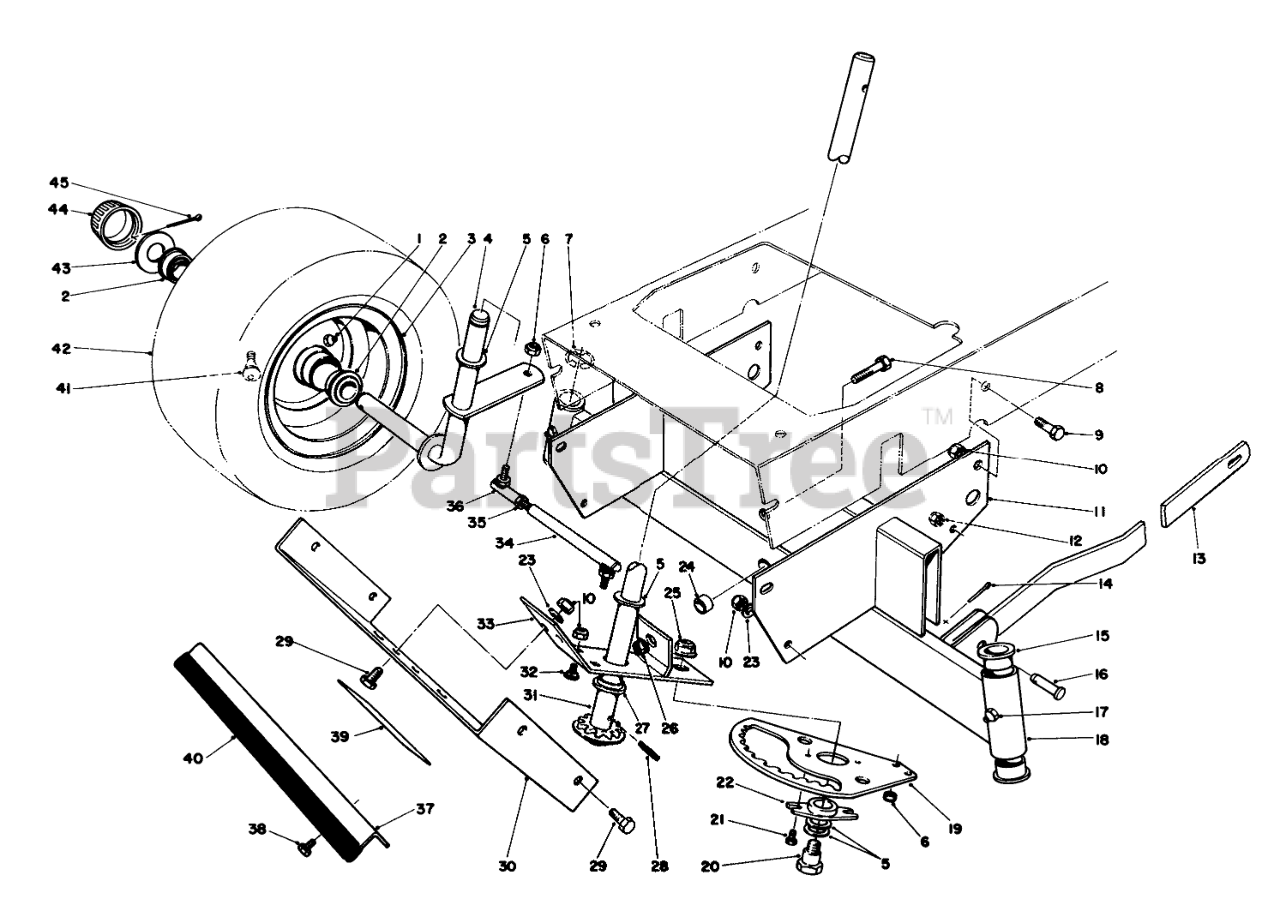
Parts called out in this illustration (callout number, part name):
1	FITTING-GREASE
2	Bearing
4	Spindle RH
5	WASHER-THRUST
6	NUT-LOCK
7	E-RING
8	SCREW-HH
9	SCREW-HH
10	NUT-LOCK, NI
11	Support
12	NUT-LOCK, CONE
13	Arm-Suspension, Front
14	PIN-COTTER
15	BEARING-FLANGE
16	PIN-CLEVIS
17	GREASE FITTING
18	Axle-Front (Incl. Ref. #15 & 17)
19	STEERING RACK B
21	SCREW
22	BUSHING-SECTOR
23	WASHER-PLAIN
24	SPACER-AXLE, FRONT
25	NUT-HF
26	NUT-HF
27	BEARING-FLANGE
28	PIN-ROLL, SLOTTED
29	SCREW-HH
30	Cover-Front
31	STRG SHAFT WA
32	SCREW-CARR
33	Bracket-Steering Rack (Incl. Ref. #27)
34	Tie Rod-Steering (Incl. Ref. #35 & 36)
35	NUT-JAM
36	JOINT-BALL
37	FRONT GUARD R
38	SCREW-HWHTF
39	Decal-Warning
40	TRIM-FRONT GUARD
41	STEM-VALVE
42	TIRE,PNEU.11X4.00X5
43	WASHER-PLAIN
44	CAP-HUB
45	PIN-COTTER
